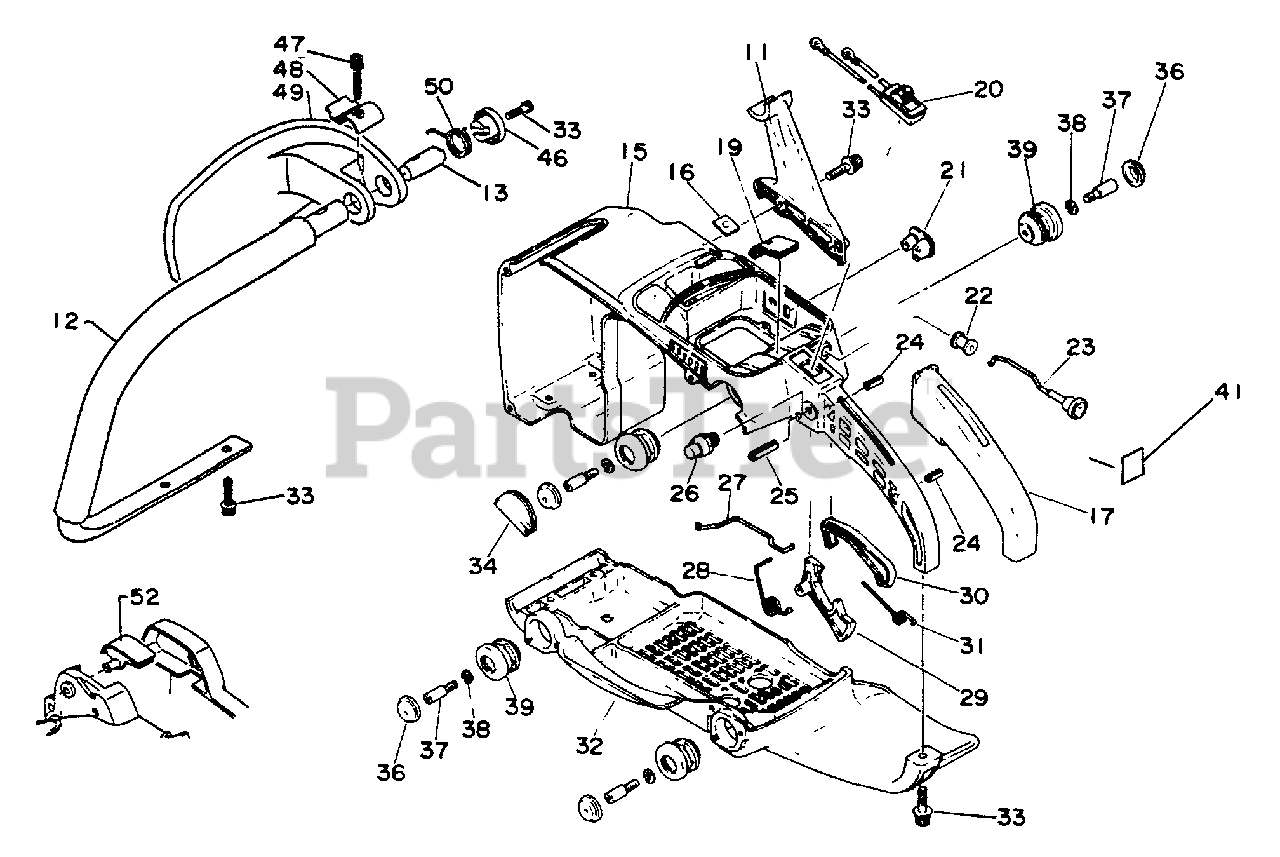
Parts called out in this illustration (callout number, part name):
11	BRACKET, HANDLE - UPPER
12	HANDLE - FRONT
15	HANDLE - REAR
17	GRIP, HANDLE - REAR
19	GROMMET
20	SWITCH, IGNITION
21	GROMMET
23	ROD, CHOKE
24	PIN - SPRING -- 4X13
25	PIN - SPRING -- 5X25
26	LATCH, THROTTLE
27	ROD, THROTTLE
28	SPRING, TRIGGER
29	TRIGGER, THROTTLE
30	LOCKOUT, THROTTLE
31	SPRING, LOCKOUT LEVER
32	SUPPORT
33	SCREW - 5X20
34	COVER, CUSHION
36	CAP, CUSHION
38	LOCKWASHER - 5
39	CUSHION
41	LABEL - CHOKE
46	RETAINER
47	SCREW - 5X35
48	STOPPER
49	GUARD
52	COVER
